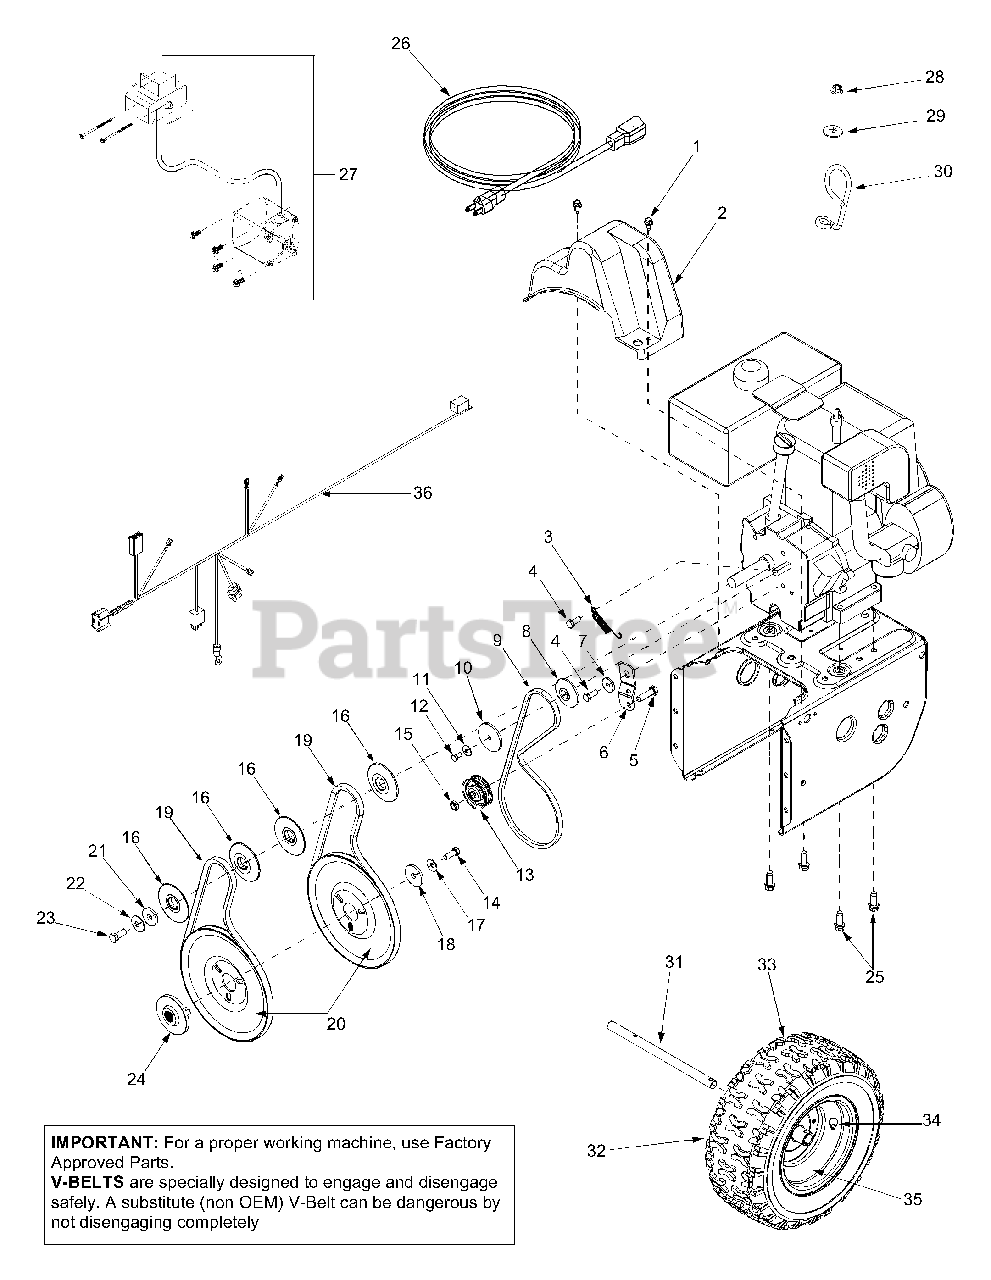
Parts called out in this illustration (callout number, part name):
1	Hex Washer Screw 1/4-20 x .625
2	Belt Cover
3	Extension Spring
4	Hex Screw 5/16-24 x .75
5	Hex Cap Screw 3/8-16 x 1.25
8	Pulley Half
9	V-Belt
10	Pulley Half
11	Bell Washer
12	Hex Cap Screw 1/4-28 x .50
13	Flat Idler
14	Lock Hex Cap Screw 5/16-24
15	Lock Jam Nut 3/8-16
16	Pulley Half
17	Bell Washer
18	Flat Washer
19	Belt
20	Auger Pulley
21	Flat Washer 3/8 x 1.25 OD
22	Bell Washer
23	Hex Cap Screw 3/8-24
24	Adapter Pulley
25	Hex Screw 3/8-16 x 1.0
26	Extension Cord
27	Electric Start Kit
28	Lock Nut, 1/4-20
29	Flat Washer, .28 x .74 x .063
30	Cable Guide
31	Axle: .75 dia. x 12.2" Lg.
34	Tubeless Air Valve
